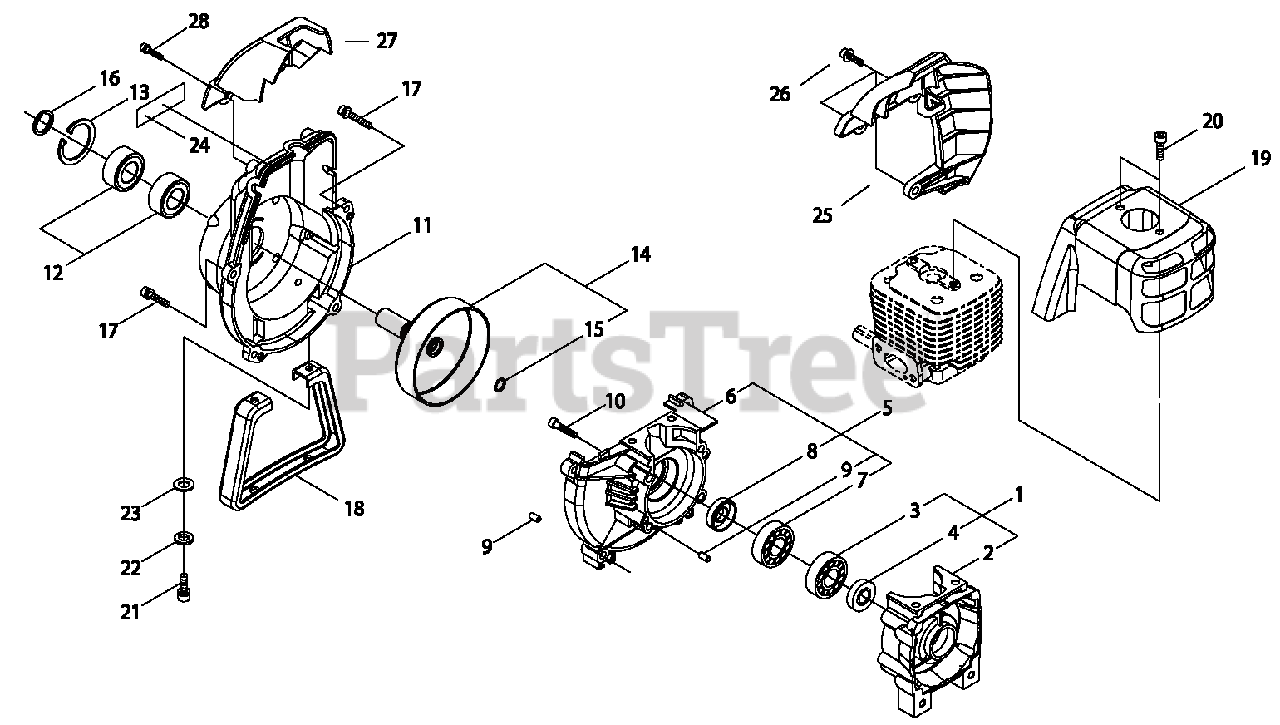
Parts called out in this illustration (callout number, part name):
1	CRANKCASE KIT - REAR
2	CRANKCASE - REAR
3	BEARING, BALL - 6202C3
4	SEAL, OIL - 15
5	CRANKCASE KIT - FRONT
6	CRANKCASE - FRONT
7	BEARING, BALL - 6202C3
8	SEAL, OIL - 15
9	PIN - LOCATING
10	SCREW - 5X30
11	CASE, FAN
12	BEARING, BALL - 6002
13	RING, RETAINING - 32
14	CLUTCH DRUM KIT
15	RING, RETAINING - 11
16	RING, RETAINING
17	SCREW - 5X20
18	GUARD, FUEL TANK
19	COVER, ENGINE
20	SCREW - 5X14
21	SCREW
22	LOCKWASHER - 5
23	WASHER - 5
24	LABEL - MODEL
25	PROTECTOR ASSY
26	SCREW - 4X16
27	PROTECTOR
28	SCREW - 4X16
